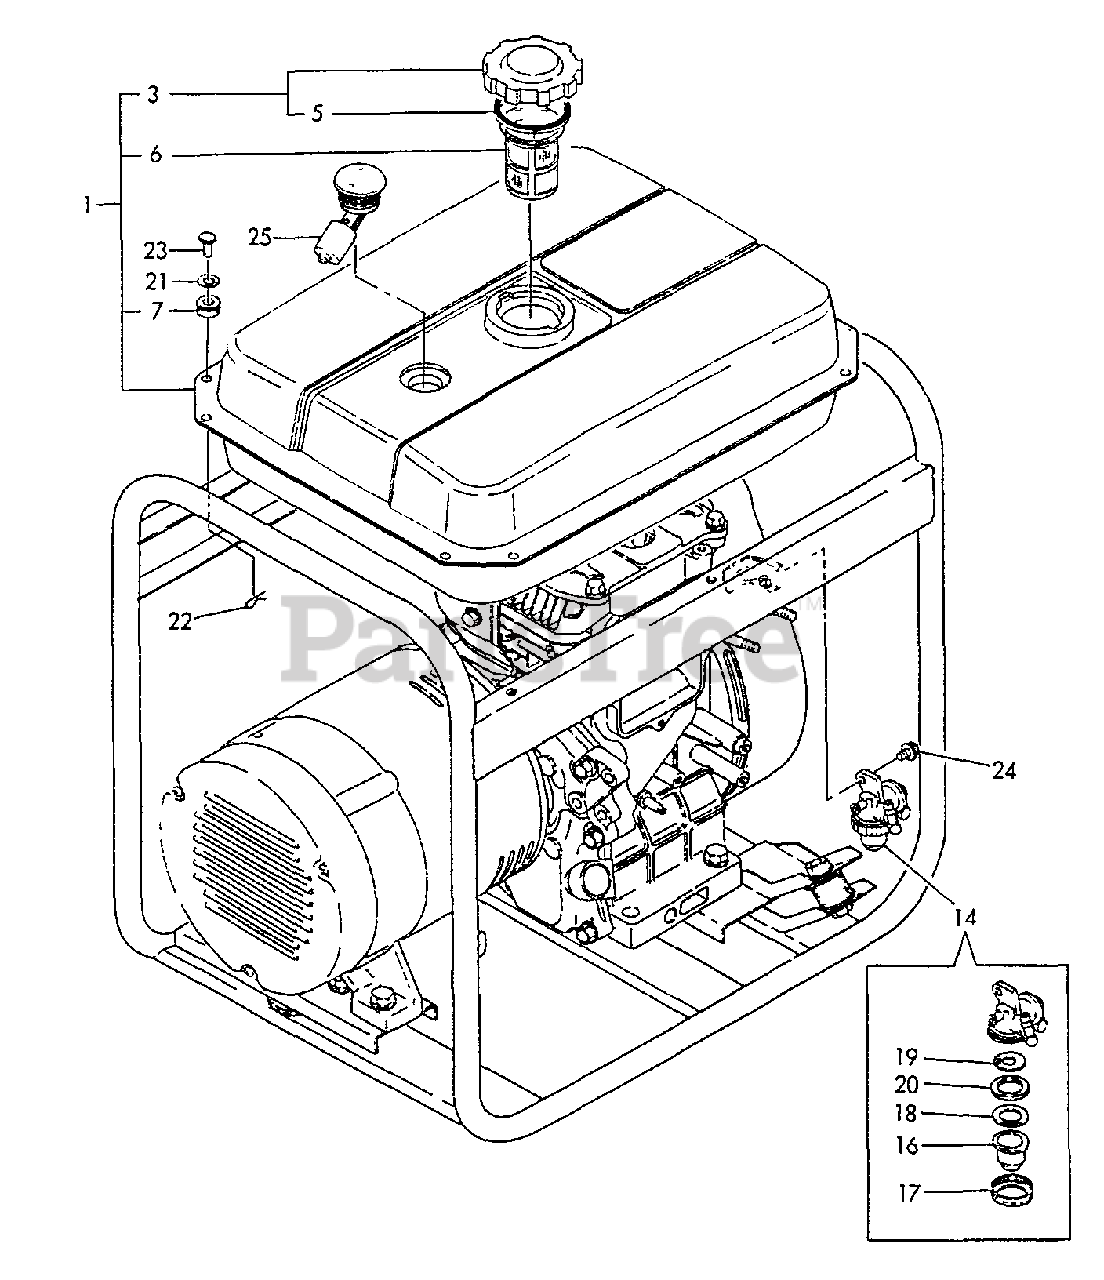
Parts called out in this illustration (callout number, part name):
1	FUEL TANK ASSY
3	CAP ASSY
5	GASKET
6	STRAINER, FUEL
7	GROMMET
14	COCK ASSY, FUEL
16	BOWL, STRAINER
17	RETAINER
18	GASKET
19	FILTER, FUEL
20	PLATE
21	WASHER
22	PIN - 6 -- SNAP
23	PIN M6×14
24	BOLT - 6×8 -- PLATED
25	GAUGE, FUEL
